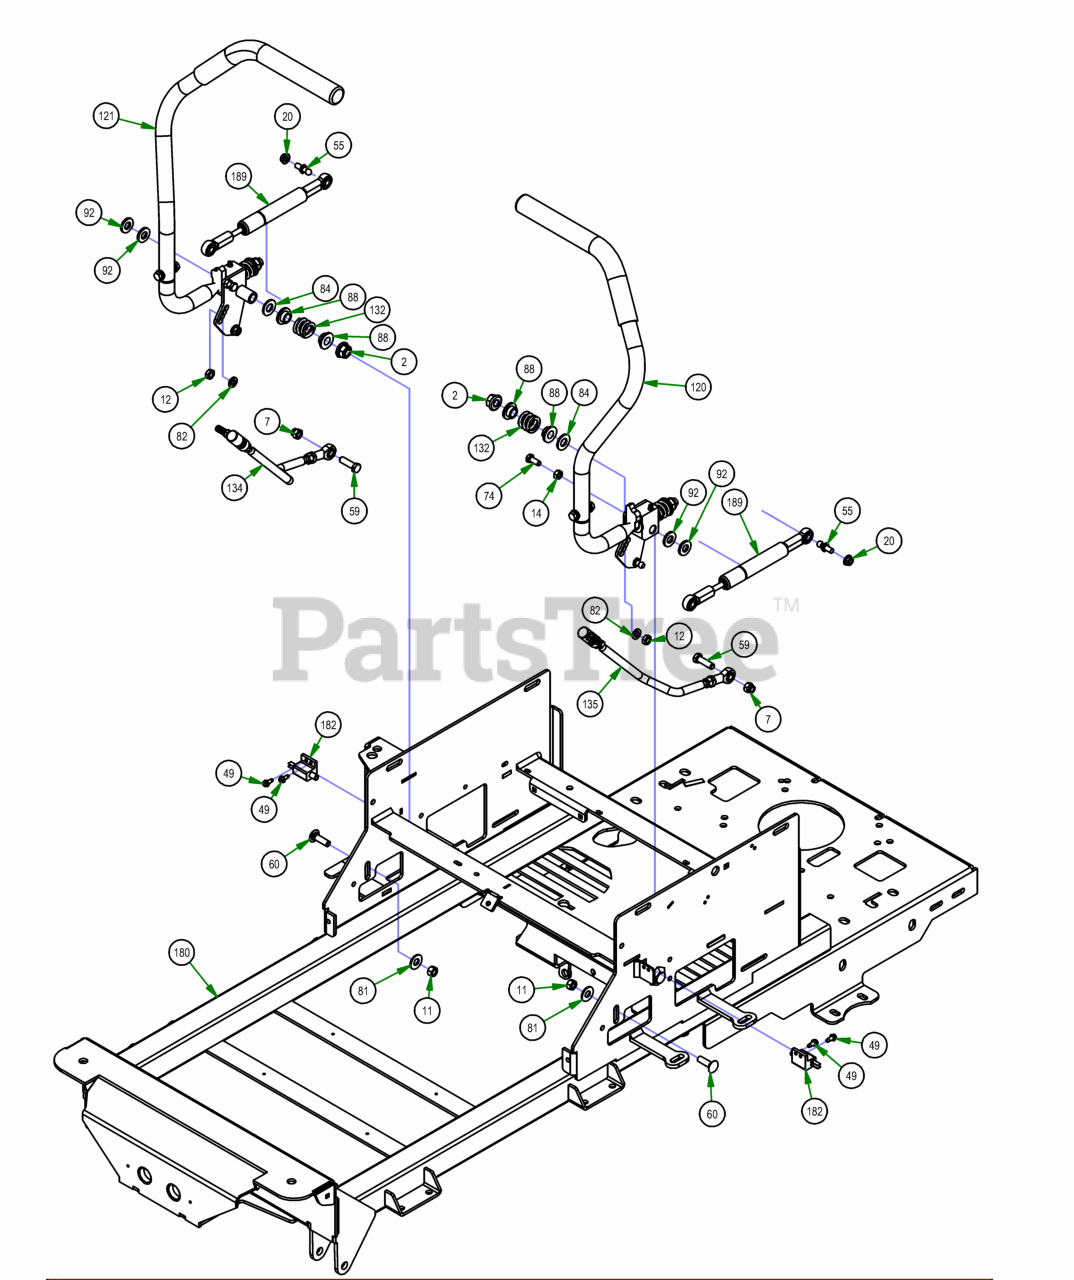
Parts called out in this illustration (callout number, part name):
2	1/2-13 HEX FLANGE AUTO OVAL LOCKNUT (GR.F) ZINC/WAX
7	3/8-16 NYLON INSERT LOCKNUT ZINC
11	3/8-16 HEX NUT ZINC
12	3/8-24 HEX NUT ZINC YELLOW
14	5/16-18 HEX NUT ZINC
20	5/16-18 HEX SERRATED FLANGE NUT HARD/ZINC
49	12-24 X 1/2 HEX WASHER UNLSOT F TCS ZINC
55	10mm Damper Ball Stud-XP Linkage
59	3/8-16 X 1-1/4 HEX CAP SCREW (GR.5) ZINC
60	3/8-16 X 1-1/4 CARRIAGE BOLT ZINC
74	5/16-18 X 3/4 HEX CAP SCREW (GR.5) ZINC
81	3/8 FLAT WASHER USS (1" OD) ZINC
82	3/8 SPLIT LOCKWASHER ZINC
84	1/2 SAE FLAT WASHER (1-1/16" OD) GR.8 ZINC YELLOW
88	.525 ID SHOULDER WASHER NYLON
92	.505 ID X 1.000 OD X .125 THICK FLAT WASHER NYLON
120	ZT Steering Arm Assembly, Left Hand
121	ZT Steering Arm Assembly-Right Hand
132	Drive Lever Spring
134	Push Rod-Right
135	Push Rod-Left
180	2021 ZT Frame - Painted
182	Safety Switch
189	Steering Damper
